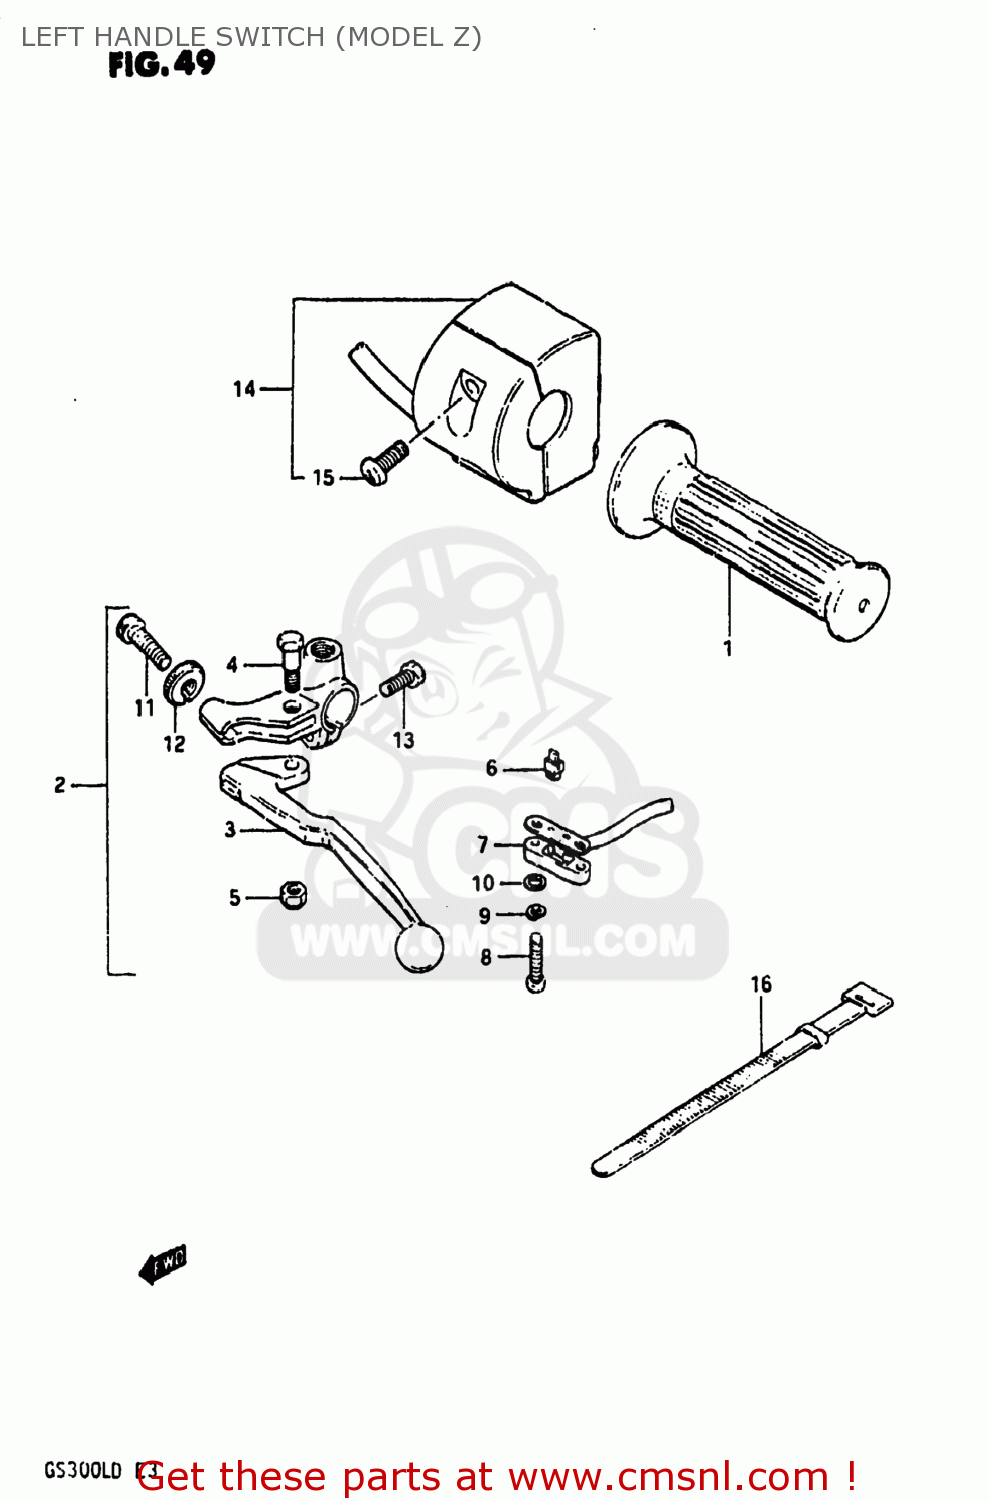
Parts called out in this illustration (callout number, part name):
1	GRIP,LEFT
2	LEVER ASSEMBLY
3	LEVER,CLUTCH
4	BOLT,LEVER
5	NUT 6MM
6	CONTACT,SWITCH
7	COVER,FR BK TERMINAL BASE
8	SCREW
9	LOCK WASHER
10	WASHER
11	ADJUSTER,CABLE
12	NUT,CABLE ADJUSTER
13	BOLT,CLUTCH LEVER HOLDER
14	SWITCH ASSEMBLY,HANDLE,LEFT
15	SCREW
16	CLAMP(L:120)
17	BUTTON,STARTER
18	SPRING,STARTER BUTTON
19	CONTACT,STARTER BUTTON
